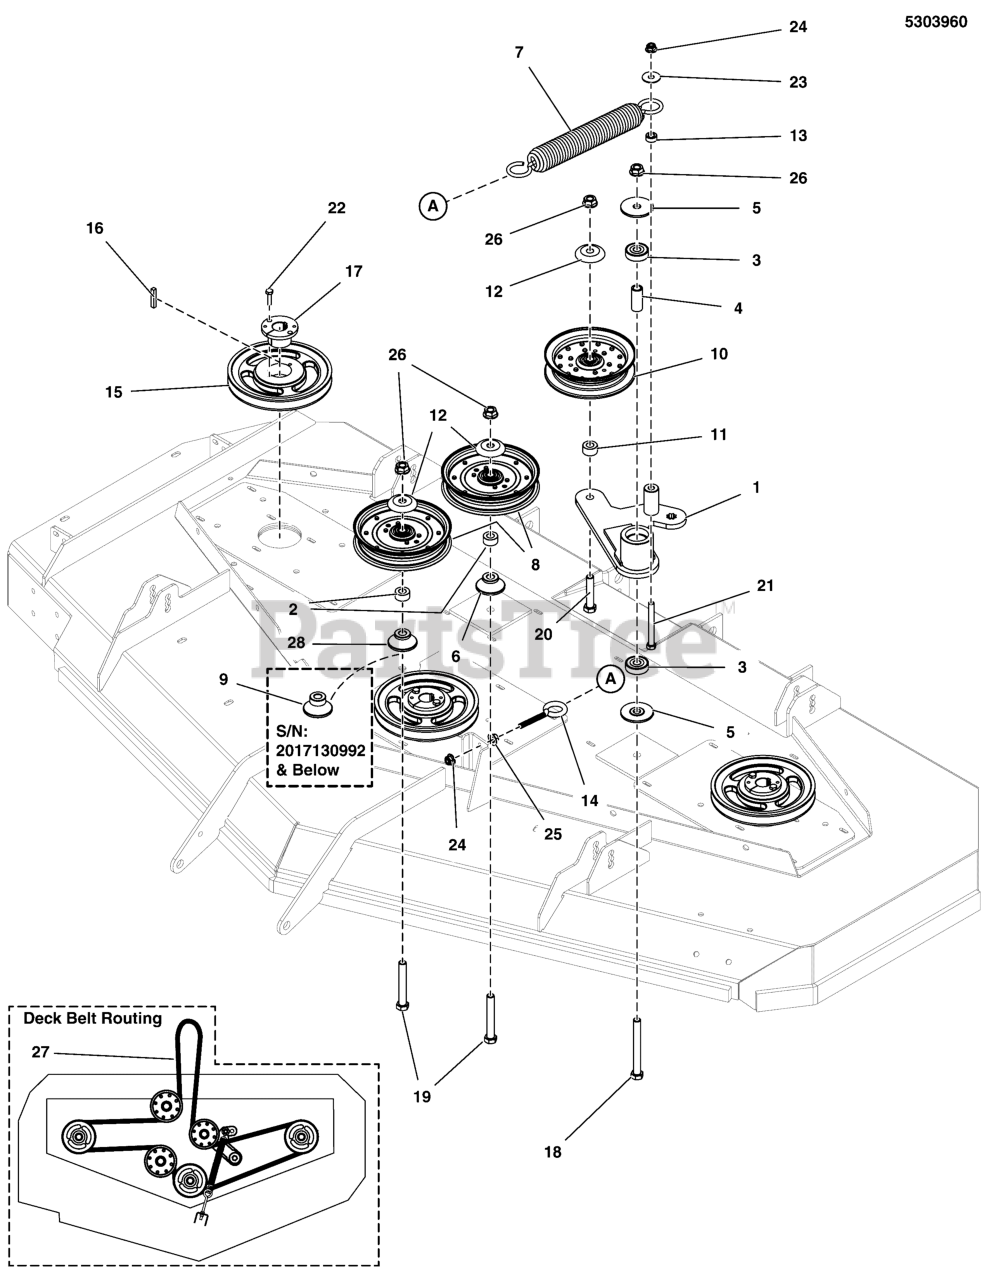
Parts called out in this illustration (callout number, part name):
1	WELD, IDLER ARM, CUTTER DECKS - BLK
2	SPACER, .52 X 1.00 X .50, CZ
3	BEARING, 6203-1/2", SEALED
4	SPACER, .510 X .750 X 1.749, CZ
5	SPACER, IDLER ARM, 1/2 X 2.25
6	IDLER MOUNT, .88 HIGH
7	SPRING, EXT, 1.5ODX12.25X.234WIRE BLK
9	IDLER MOUNT
11	SPACER, .52 X 1.00 X .56, PM, CZ
12	SHIELD, PULLEY BEARING, CZ
13	SPACER, .38 X 1.13 X .781 STEP, CZ
14	EYEBOLT, 3/8-16 X 4, 2.13THRD, .75EYE, C
15	PULLEY, 7.632"OB, HQ BORE, SPLIT STEEL
16	KEY 1/4 SQ X 1 1/2 LONG
17	BUSHING, TAPERED HUB
18	BOLT, 1/2-13 X 4-1/2 GD5 CZ
19	BOLT, 1/2-13 X 3-1/2, HEX HD, GD5, CZ (SV)
20	BOLT, 1/2-13 X 2-1/2" GD5 CZ
21	BOLT, 3/8-16 X 4" GD5 CZ
22	BOLT, 1/4-20 X 1" GD5 CZ
23	WASHER-3/8 FENDER
24	NUT, 3/8-16 HEX NYLOCK FLANGE
25	NUT, 3/8-16 HEX SERRATED FLANGE
26	NUT, Hex Flange, Nylock, 1/2-13
27	BELT, SPB/XPB 193.9" EL, LRG ARAMID, 2T
28	IDLER MOUNT, .88 HIGH
